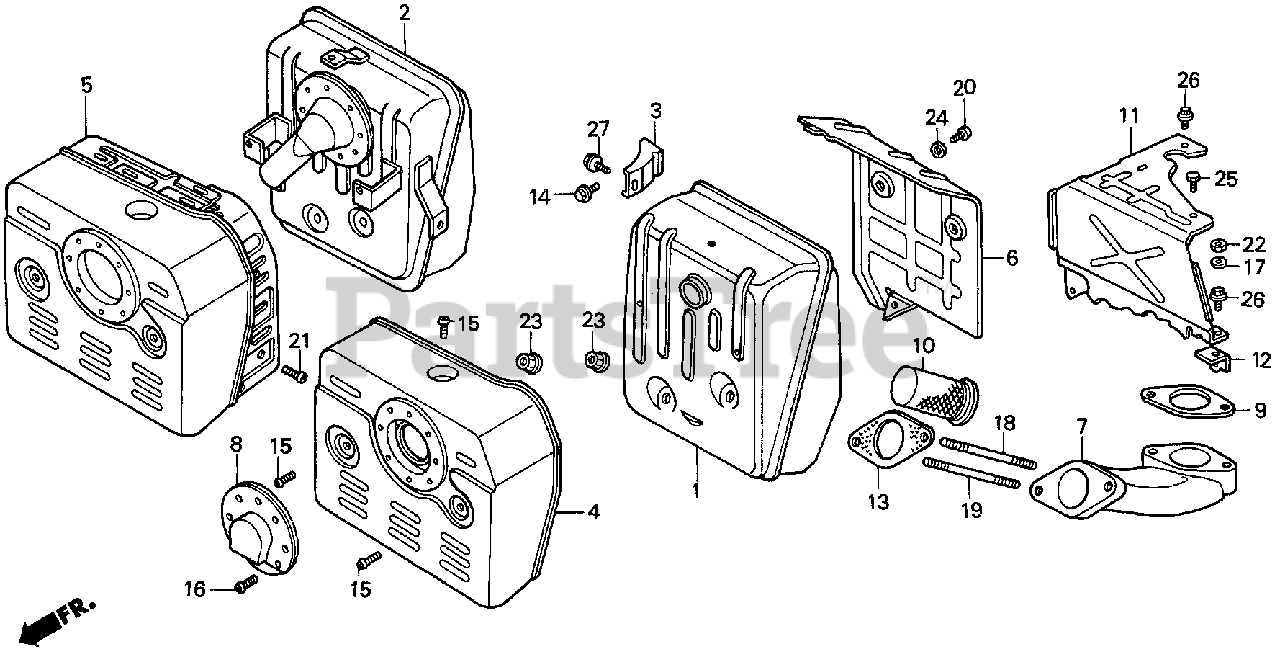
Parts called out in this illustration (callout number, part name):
1	MUFFLER
3	STAY, MUFFLER
4	PROTECTOR, MUFFLER (Honda Code 2106292). (NOT AVAILABLE)
6	SEPARATOR, MUFFLER
7	PIPE, EX.
8	CAP, MUFFLER
9	GASKET, EX. PIPE
9	GASKET, EX. PIPE (WACKER)
10	ARRESTER, SPARK
11	COVER (LOWER)
12	STAY, COVER (LOWER)
13	GASKET, EX. PIPE
14	BOLT, FLANGE (8X16)
15	SCREW, TAPPING (5X8)
16	SCREW, TAPPING (4X6)
17	RUBBER (LOWER)
18	BOLT, STUD (8X60)
19	BOLT, STUD (8X70)
20	SCREW, PAN (6X6)
22	NUT, HEX. (6MM)
23	NUT, FLANGE (8MM)
24	WASHER, PLAIN (6MM)
25	BOLT, FLANGE (6X10)
26	BOLT, FLANGE (6X12)
27	BOLT, FLANGE (8X14)
